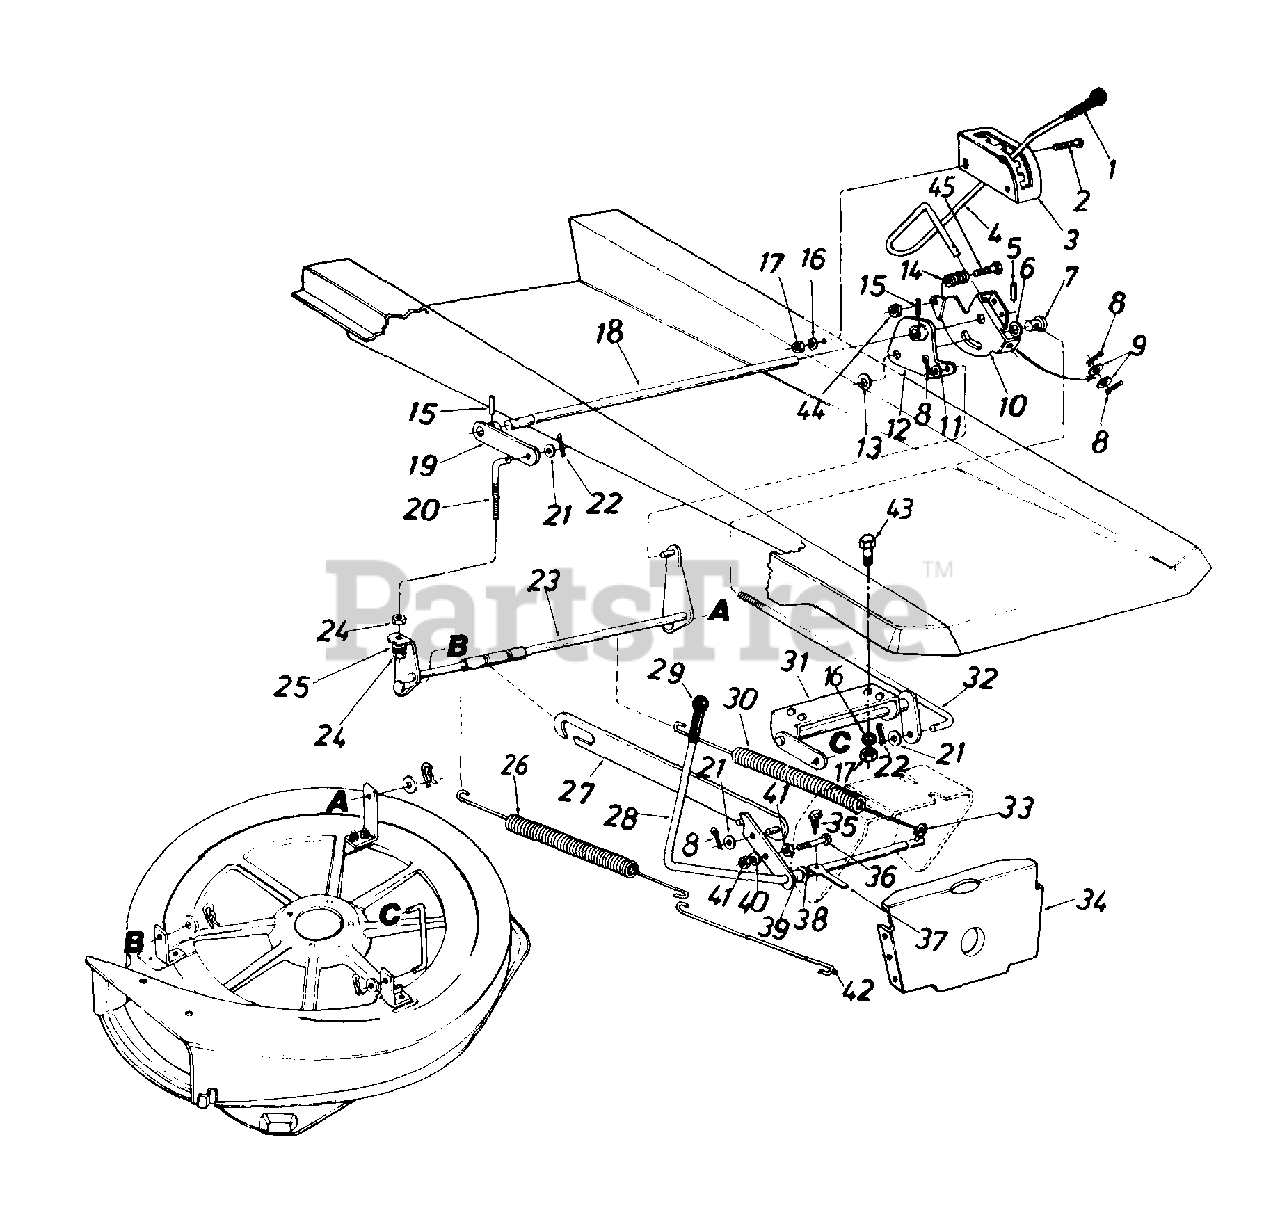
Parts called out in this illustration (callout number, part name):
2	Truss Mach. Scr. 5/16-18 x .75" Lg.
5	Spring Pin Spir. 3/16" Dia. x 1.50" Lg.
6	Fl-Wash..385" I.D. x .87" O.D.
7	Adj. Ferrule Deck Lift Handle
8	Cotter Pin 1/8" Dia. x 1.0"
9	Fl-Wash. .531" I.D. x .930" O.D.
12	Deck Lift Brkt. Ass'y. - L.H.
13	Fl-Wash. .635" I.D. x 1.04" O.D.
14	Compression Spring .5" Dia. x .9" Lg.
15	Spring Pin Spir. 1/4" Dia. x 1.50" Lg.
16	L-Wash. 5/16" I.D.
17	Hex Nut 5/16-18 Thd.
18	Rear Hgt. Adj. Shaft
19	Deck Lift Brkt. Ass'y. - R.H.
20	Deck Adj. Scr. 3/8-16 Thd.
21	Fl-Wash. .385" I.D. x .87" O.D.
22	Intern. Cotter Pin 1/2" Dia.
23	Deck Link Ass'y. - Rear
24	Hex Nut 3/8-16 Thd.
25	L-Wash. 3/8" I.D.
26	Extension Spring 13.84" Lg.
30	Extension Spring .73" O.D. x 13.84" Lg.
31	Deck Lift Ass'y. - Front
32	Deck Lift Connecting Rod
33	Clevis Pin Special .250" Dia.
36	Hex Bolt 5/16-18 x 1.50" Lg. (Grade 5)
37	Switch Actuator
38	Fl-Wash. .531" I.D. x .930" O.D.
39	Spacer .511" I.D. x .70" O.D. x .38" Lg.
40	L-Wash. 5/16" I.D.
41	Hex Nut 5/16-18 Thd.
42	Spring Hook
43	Hex Bolt 5/16-18 x .75" Lg.
44	Hex Cent. L-Nut 1/4-20 Thd.
45	Hex Bolt 1/4-20 x 1.25" Lg.
